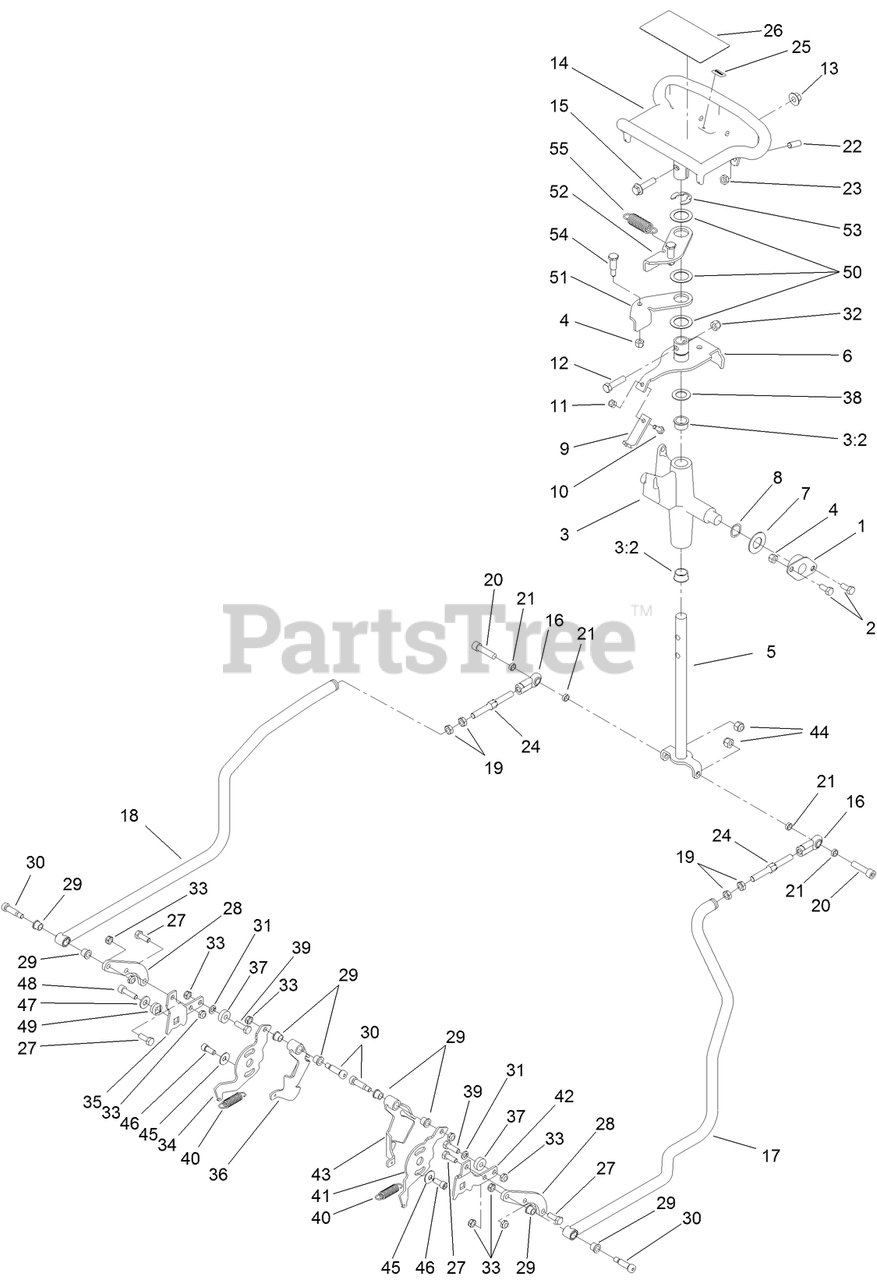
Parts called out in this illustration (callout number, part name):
1	BUSHING
2	SCREW-HH
3	CONTROL SUPPORT ASM
3:2	BEARING-FLANGE
4	NUT-LOCK, NI
5	ROD-DRIVE
6	LEVER-PIVOT
7	WASHER-FLAT
8	WASHER-SPRING, WAVE
9	PLATE-NEUTRAL
10	SCREW-HH
11	NUT-LOCK, NI
12	SCREW-HH
13	NUT-FLANGE
14	HANDLE-CONTROL
15	SCREW-HHF
16	JOINT-BALL END, LH
17	ROD-CONTROL, LH
18	ROD-CONTROL, RH
19	NUT-HJ
20	SCREW-HSH
21	SPACER-PLATE, RETAINING
22	SCREW-SET
23	NUT-JAM
24	LINK-CONTROL, ADJUSTMENT
25	DECAL
26	DECAL-TRACTION
27	SCREW-HH
28	PLATE-ADAPTER, CONTROL, RH
29	BUSHING-FLANGE
30	BOLT-SHOULDER
31	WASHER-LOCK
32	NUT-LOCK, NI
33	NUT-LOCK, NI
34	PLATE-BASE, RH
35	PLATE-ARM, RETURN
36	PIVOT-RH
37	BEARING-BALL
38	WASHER-THRUST
39	SCREW-HH
40	SPRING-EXTENSION
41	PLATE-BASE, LH
42	PLATE-ARM, RETURN, LH
43	PIVOT-LH
44	NUT-LOCK, NI
45	WASHER-BELLEVILLE
46	SCREW-HSH
47	WASHER-FLAT
48	SCREW-HSH
49	LOCK-TRUNION
50	WASHER-PLAIN
51	LEVER-RETURN, RH
52	LEVER-RETURN, LH
53	RING-RETAINING
54	SCREW-SHOULDER
55	SPRING-EXTENSION
